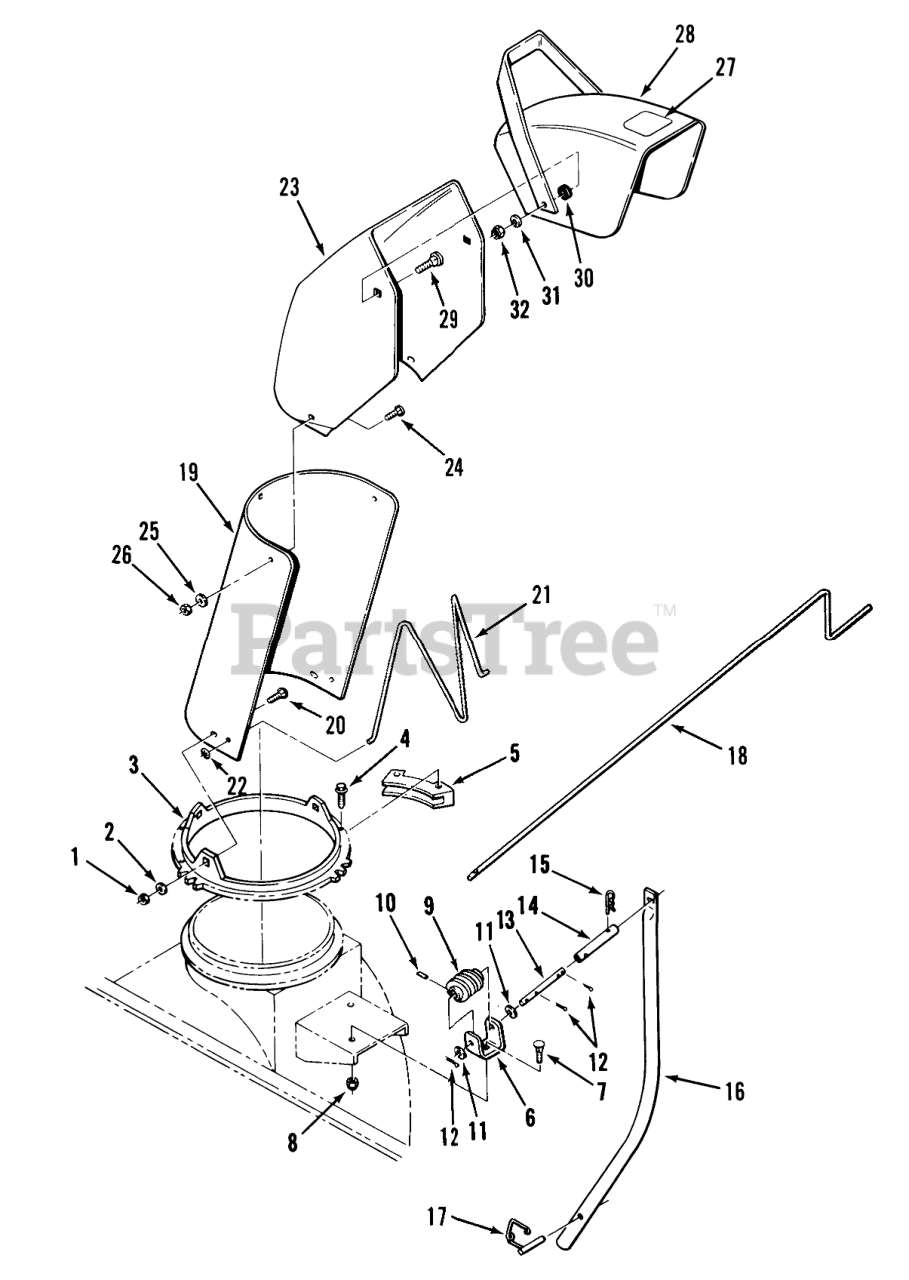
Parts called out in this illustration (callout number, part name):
1	Nut
2	WASHER 5/16 SAE
3	Screw
4	SCREW-SPECIAL
5	RETAINER-CHUTE
6	WORM BRKT B
7	Bolt
8	Nut
9	GEAR-WORM, CHUTE
10	PIN-SPRING
11	Washer
12	Cotter Pin
13	ROD-LOWER CHUTE CONT
14	COUPLING
15	Hairpin Cotter
16	TUBE-CRANK SUPPOR R
17	LOCKING PIN ASM
18	ROD-CHUTE CONTROL
19	Chute-Extender
20	Bolt
21	WIRE-CHUTE
22	NUT-PUSH
23	CHUTE-UPPER R
24	CARRIAGE BOLT -4
25	WASHER 5/16 SAE
26	Nut
27	DECAL DANGER
28	Deflector
29	Bolt
30	WASHER-RUBBER
31	WASHER-BELLEVILLE
32	Nut
